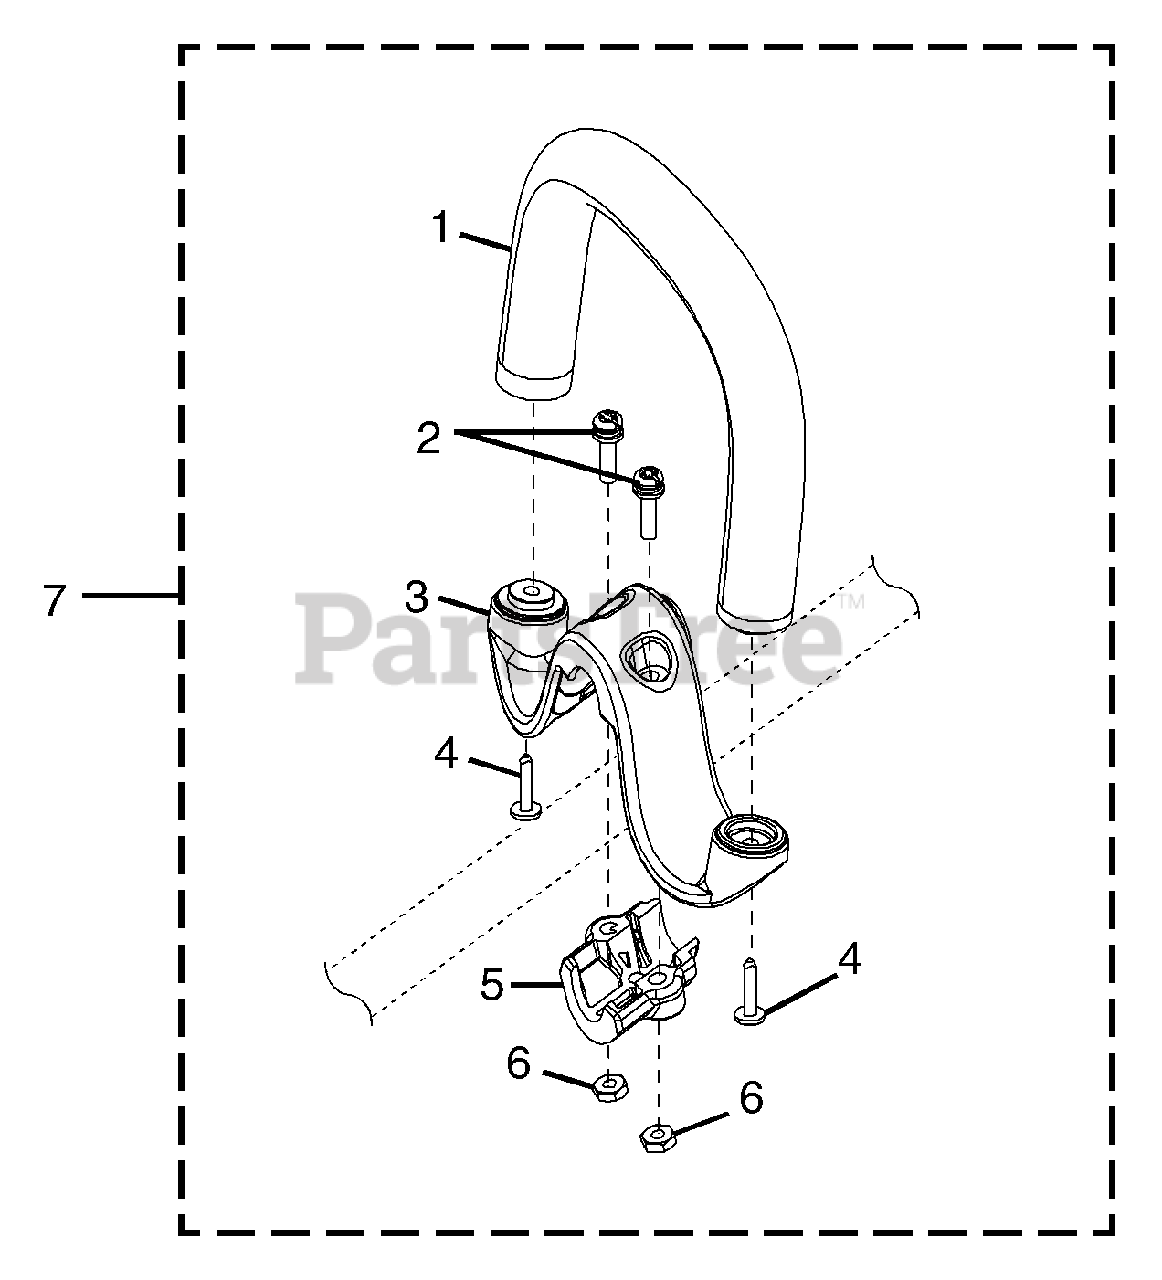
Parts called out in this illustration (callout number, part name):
1	ASSIST HANDLE W/GRIP
2	SCREW (12-24 x 1 SEMS)
3	M CLAMP
6	HEX NUT (12-14)
7	ASSIST HANDLE ASSEMBLY
